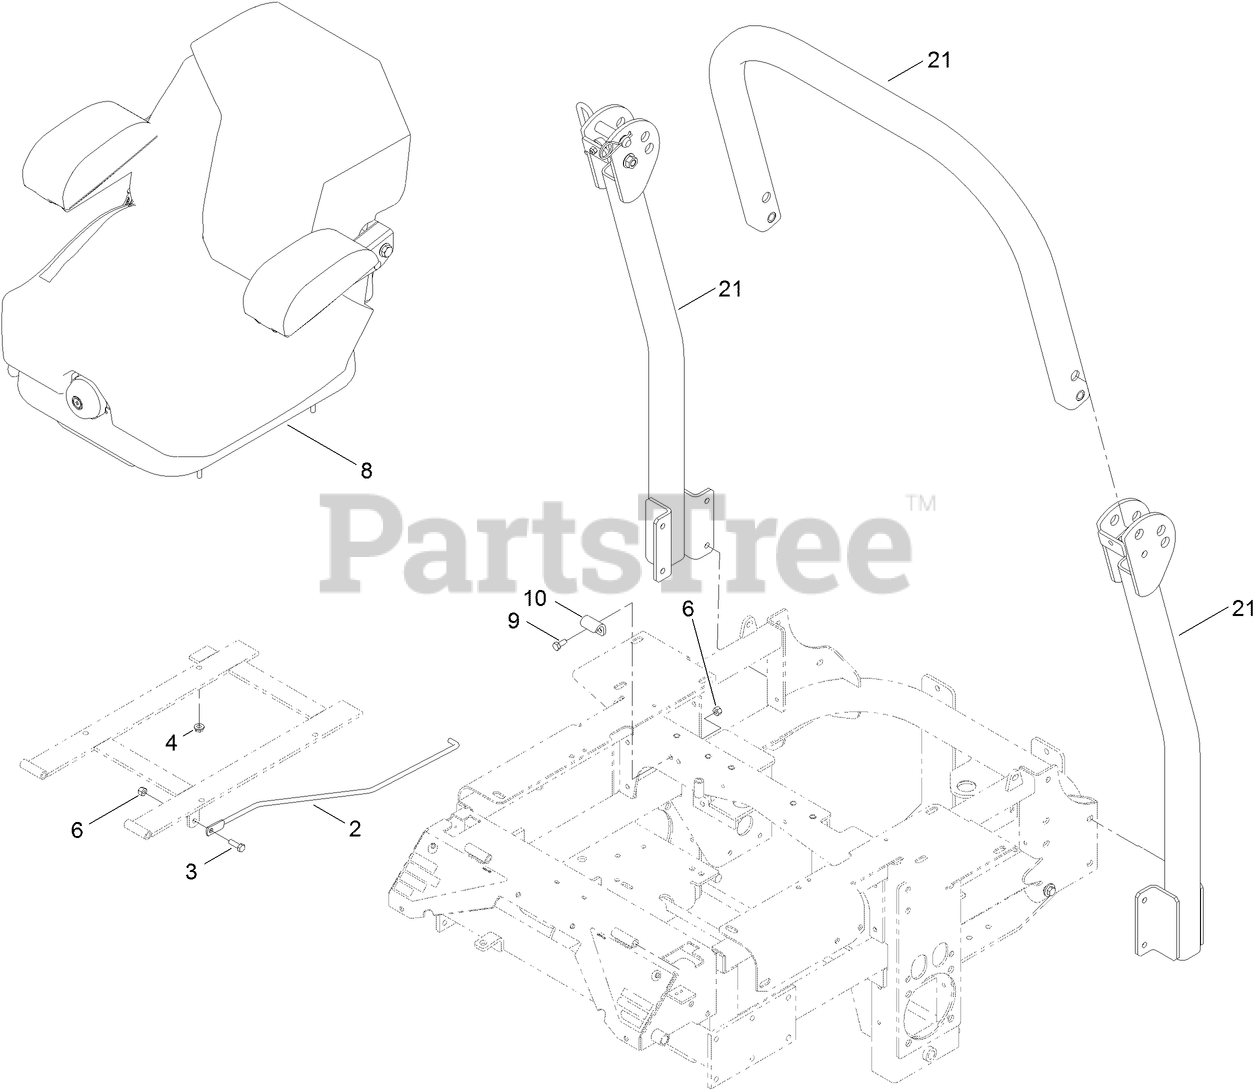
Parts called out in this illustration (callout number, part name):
2	ROD-PROP, SEAT
3	SCREW-HH
4	NUT-HF
6	NUT-LOCK, NI
8	SEAT-SUSPENSION
9	SCREW-HH
10	CATCH-LATCH, SEAT
21	ROPS KIT
